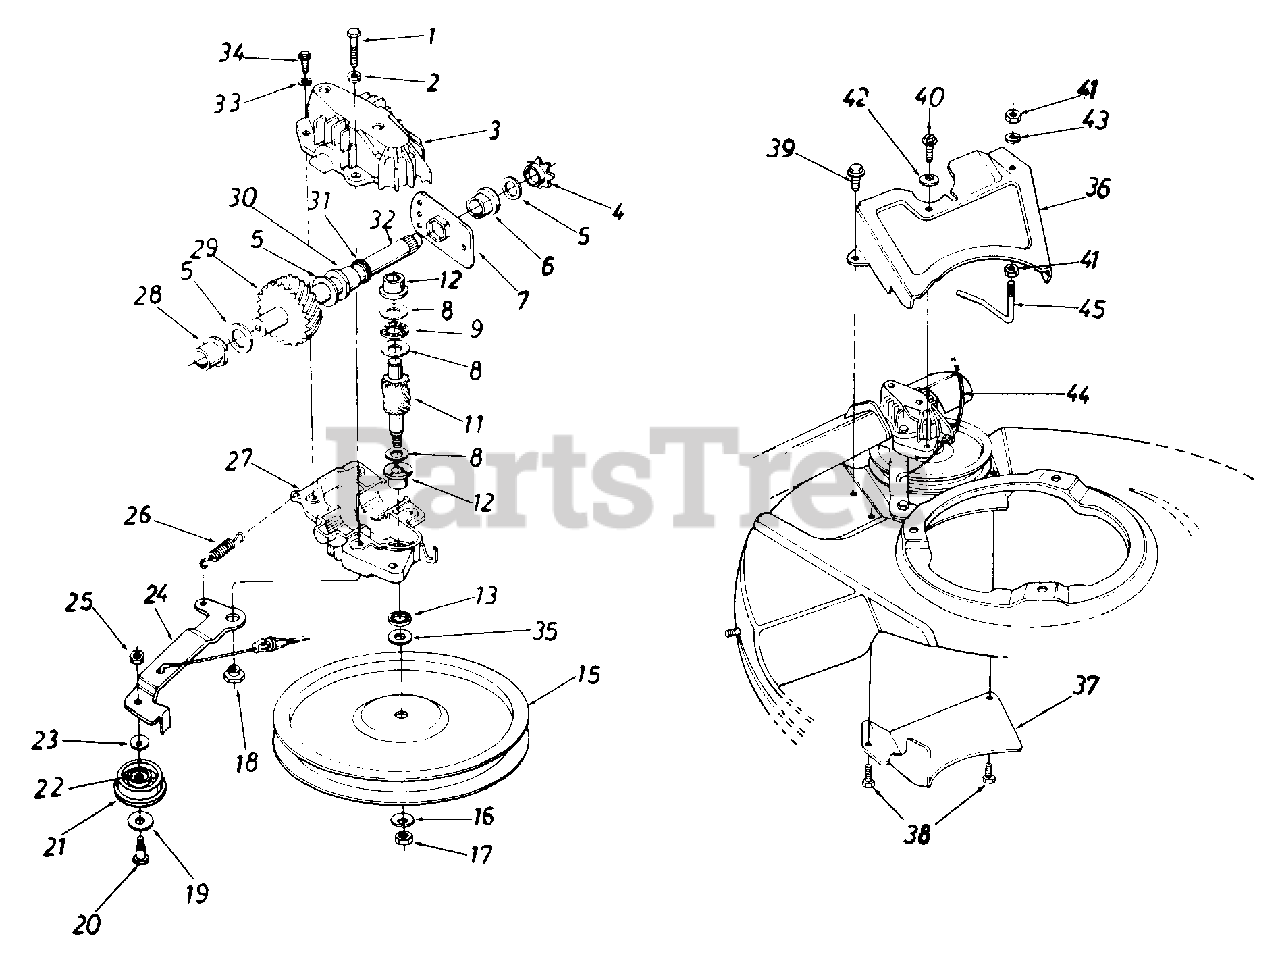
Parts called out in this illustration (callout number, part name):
1	SCREW-HEX
2	L-Wash. 1/4" I.D.
3	HOUSING HALF-UPPER
4	SPROCKET-7T
5	WASHER-FL
6	BEARING-HEX FLANGE
8	WASHER-THRUST.382 X .684
9	BEARING-THRUST
11	SHAFT-PINION 11 T
12	BEARING-FLANGE
13	SEAL-OIL-.375 ID
16	WASHER-SPRING BELL
17	NUT-LH THD-1/4 X 28
18	SPACER-SHLD
19	WASHER-FL .995 X .032
20	SCREW-SHLD
21	PULLEY
22	BEARING-NEEDLE
23	WASHER-SPRING BELL
24	BRACKET ASSY-IDLER
25	NUT-HEX 1/4-28
26	SPRING-EXTENSION
27	HOUSING HALF-LOWER
28	BEARING-FLANGE
29	SHAFT-ASSY W/GEAR
30	BEARING-FLANGE
32	SHAFT-ASSY W/GEAR
33	WASHER-LOCK-#10
34	SCREW-HEX WASH HD TAP
35	WASHER-HEX
39	SCREW-HEX WASH SF TAPP
40	SCREW-HEX B-TAP 1/4-.62
41	NUT-HEX 1/4-20
42	WASHER-SPRING BELL
43	LOCK WASHER 1/4 DIA
44	CABLE-CLUTCH
45	GUARD-BELT
